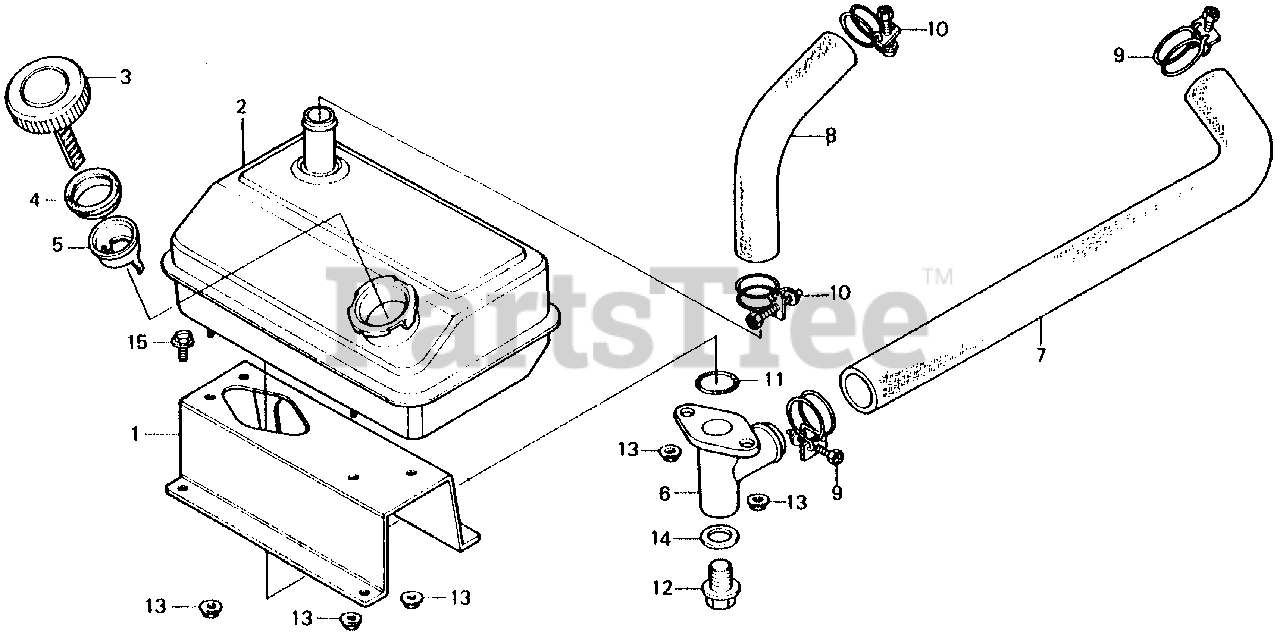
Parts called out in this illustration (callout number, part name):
1	STAY, OIL TANK
2	TANK, OIL *NH116M* (URBAN SILVER METALLIC)
4	RUBBER, FILTER (NOT AVAILABLE)
5	HOLDER, FILTER RUBBER
6	HOLDER, OIL DRAIN
7	TUBE A, OIL
8	TUBE, BREATHER
9	CLIP, WATER HOSE
10	PIPE, BAND
11	O-RING (27X2.0)
12	BOLT, DRAIN PLUG (12MM)
13	NUT, FLANGE (6MM)
14	WASHER, DRAIN PLUG (12MM)
15	BOLT, FLANGE (6X10)
